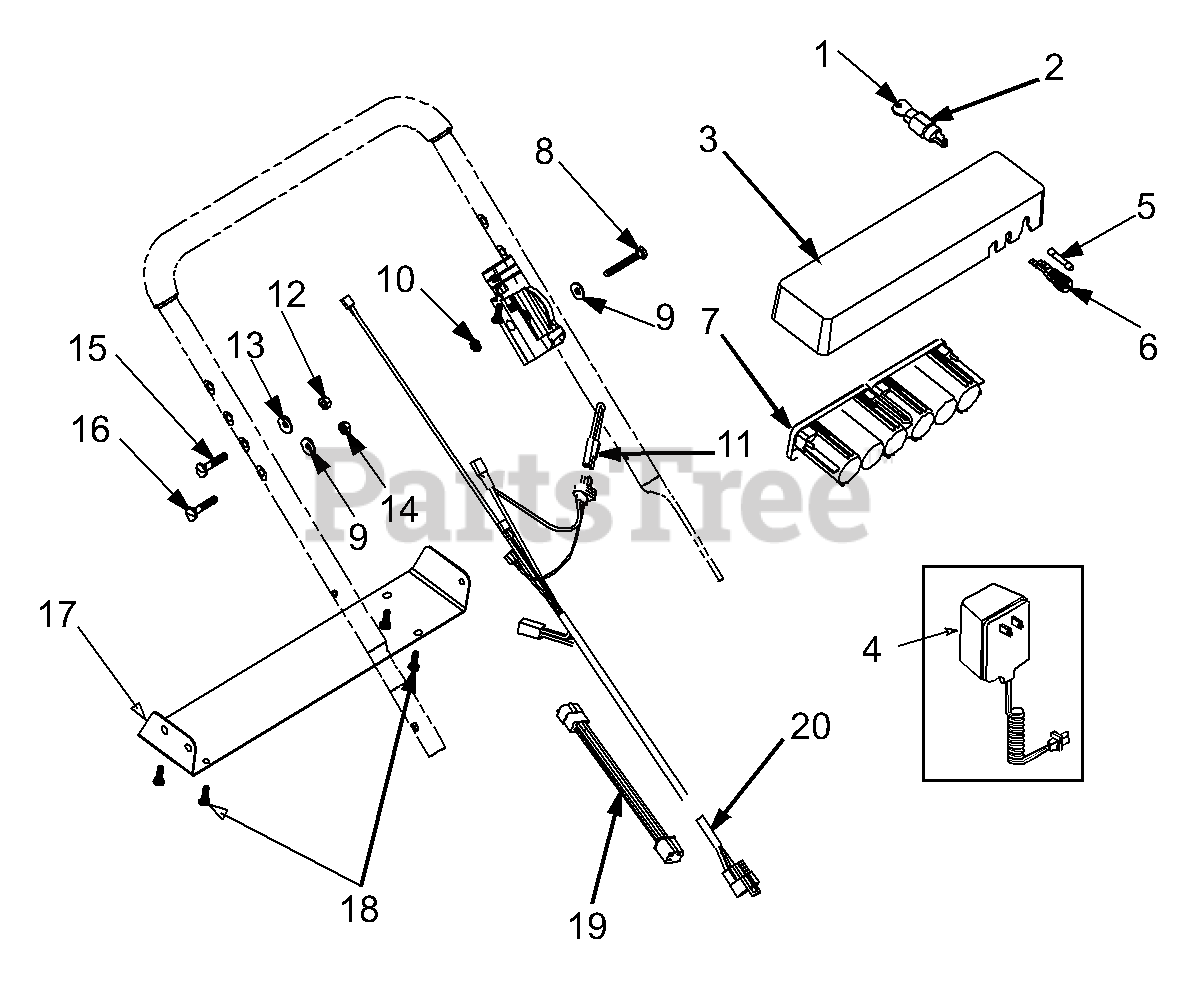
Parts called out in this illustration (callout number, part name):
1	Ignition Key
2	Key Switch
3	Battery Tray
4	Battery Charger
5	Fuse 7.5 Amp
6	Fuse Holder
7	Battery 12V
8	Hex Screw:1/4-20:2.0
9	Bell Washer
10	Special Hex Nut 5/16-18
11	Plug
12	Nut 5/16-18
13	Bell Washer
14	Hex Nut 1/4-20
15	Carriage Bolt
16	Carriage Screw
19	Harness Extension
20	Harness
